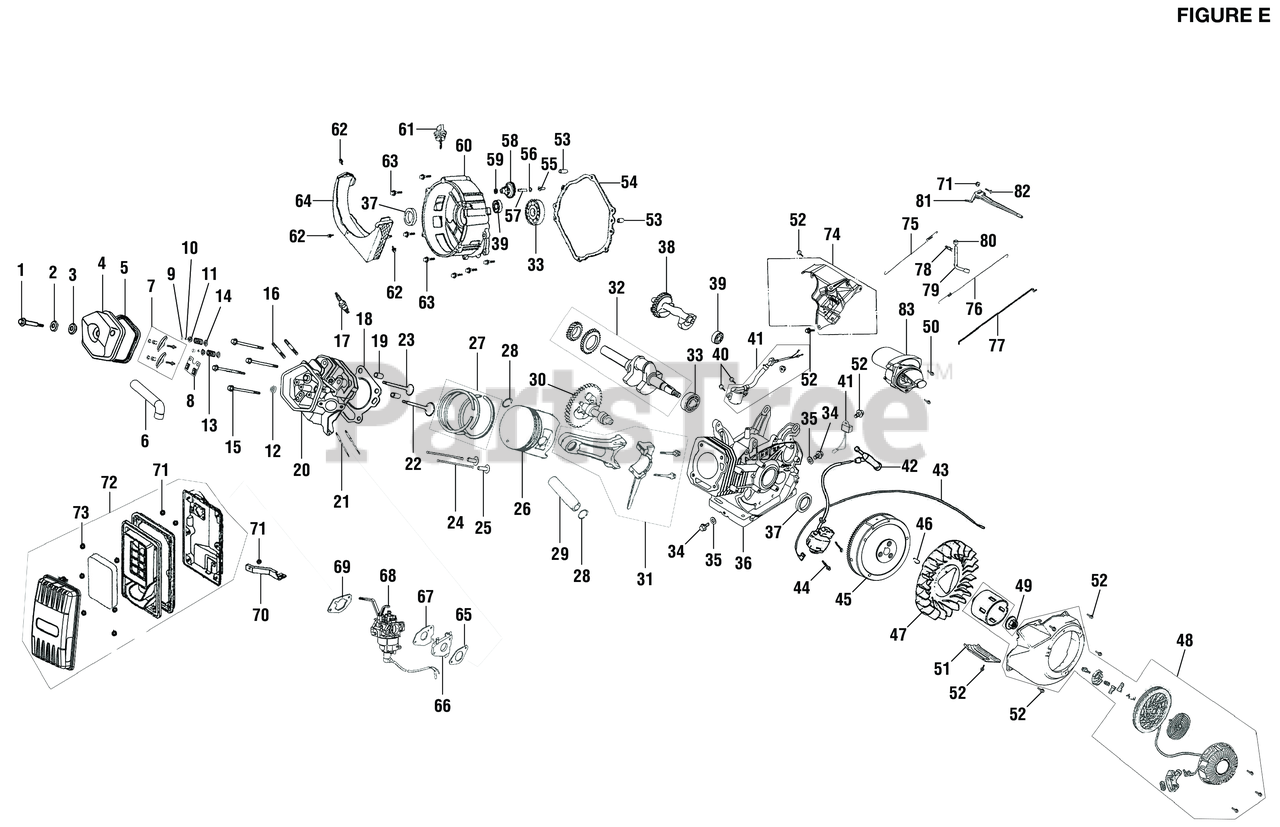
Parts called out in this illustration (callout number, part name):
1	Bolt (Cylinder Head Cover)
2	Gasket (For Bolt)
3	Oil Seal (For Bolt)
4	Cylinder Head Cover
5	Gasket (Cylinder Head Cover)
6	Hose (Cylinder Head Cover)
7	Rocker Arm Assembly
8	Push Rod Guide Plate
9	Exhaust Valve Cap
10	Valve Lock Clamp
11	Valve Spring Retainer
12	Intake Valve Guide
13	Valve Spring
14	Valve Spring Retainer
15	Stud (M10 x 80 mm)
16	Stud (M8 x 35 mm)
18	Gasket (Cylinder Head)
19	Pin (Cylinder Head)
20	Cylinder Head Assembly
21	Stud (M6 x 106 mm)
22	Intake Valve
23	Exhaust Valve
27	Piston Ring Set
30	Camshaft Assembly
31	Connecting Rod Assembly
32	Crankshaft Assembly
33	Bearing (6207)
36	Cylinder Block Assembly
38	Balancer Shaft
39	Bearing (6202)
40	Bolt (M6 x 16 mm, Flange Hex Hd.)
41	Oil Circuit-Breaker Assembly
42	Magneto Assembly
43	Ignition Wire
44	Bolt (M6 x 25 mm, Flange Hex Hd.)
45	Flywheel Assembly
48	Recoil Assembly
50	Bolt (M8 x 35 mm, Flange Hex Hd.)
52	Bolt (M6 x 12 mm, Flange Hex Hd.)
55	Governor Slider
56	Retaining Ring
60	Gear Chamber Cover
61	Oil Dipstick
62	Bolt (M5 x 8 mm, Cross Pan Hd.)
63	Bolt (M8 x 40 mm, Flange Hex Hd.)
64	Alternator Shroud
65	Intake Gasket
66	Insulator Plate
68	Carburetor Assembly
71	Hex Nut (M6)
72	Air Filter Box Assembly
73	Hex Nut (M5)
74	Governor Base Assembly
75	Governor Spring
76	Governor Spring
77	Throttle Adjusting Handle
81	Governor Arm
82	Screw (Square Hd.)
83	Starter Assembly
